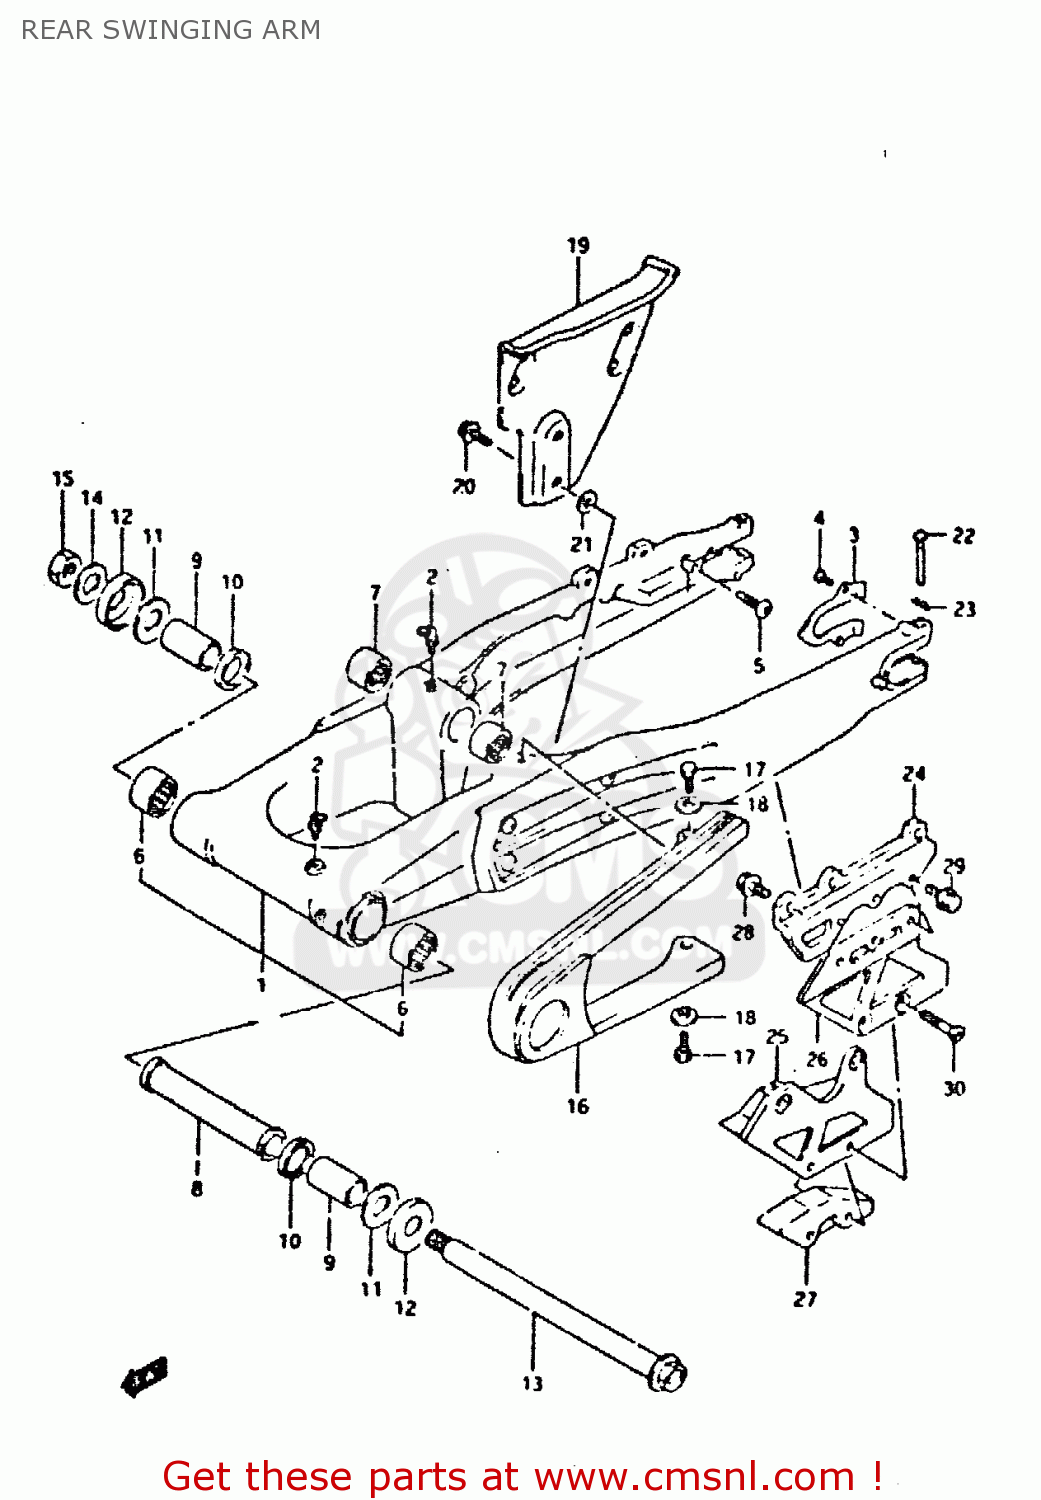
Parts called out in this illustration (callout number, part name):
1	SWINGINGARM ASSY,RR
2	NIPPLE,GREASE
3	PLATE,SWING ARM RR
4	SCREW (5X8)
5	SCREW (M10X21)
6	BEARING(22X29X30)
7	BEARING(20X27X23.5)
8	SPACER,SWING ARM PIVOT,CENTER
9	SPACER,SWGARM PIVOT BRG
10	SEAL,OIL(22X29X4)
11	WASHER
12	COVER,SWINGINGARM PIVOT
13	SHAFT,SWINGING ARM PIVOT
14	WASHER, FIXED DRIVE FACE
15	NUT
16	BUFFER,CHAIN TOUCH DEFENSE
17	BOLT
18	WASHER
19	GUARD,CHAIN
20	BOLT
21	WASHER
22	PIN
23	CLIP
24	BRACKET,CHAIN GUIDE
25	GUIDE,CHAIN
26	PLATE,CHAIN GUIDE OUTER
27	DEFENSE,CHAIN GUIDE
28	BOLT
29	BOLT
30	PIN
31	CLIP
32	PLATE SET,CHAIN GUIDE
33	WASHER
